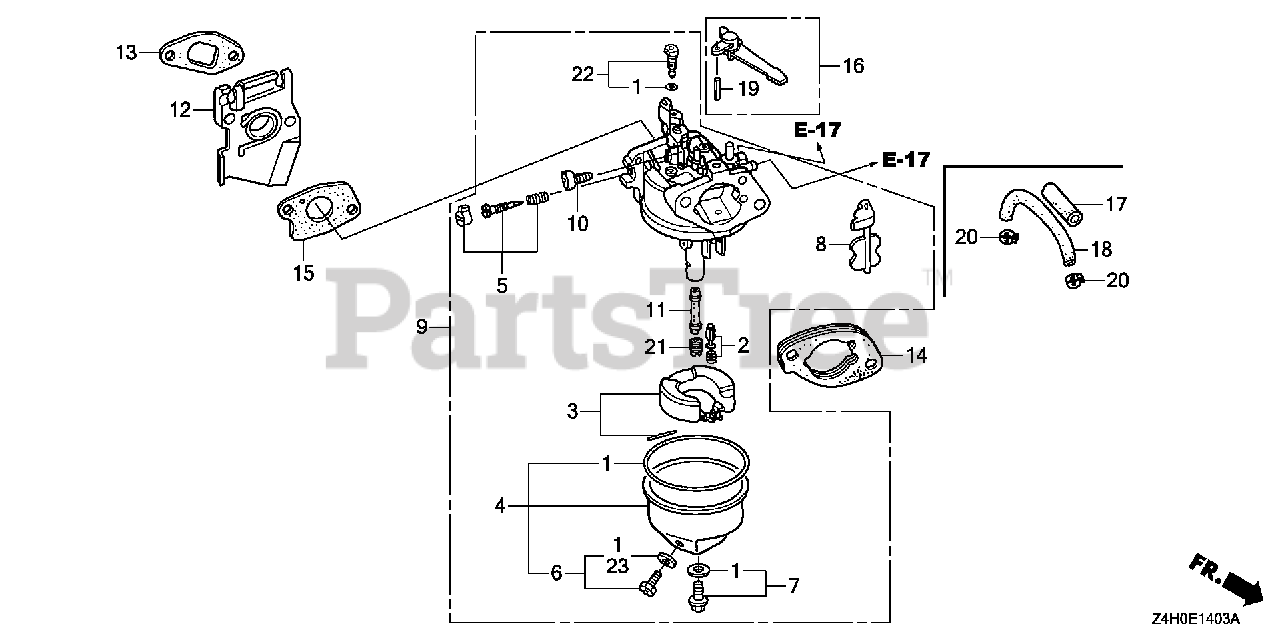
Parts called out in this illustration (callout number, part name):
1	GASKET SET
2	VALVE SET, FLOAT (SEAT NOT INCLUDED)
4	CHAMBER, FLOAT
5	SCREW SET, PILOT
6	SCREW SET, DRAIN
9	CARBURETOR ASSY. (BE62L A)
9	CARBURETOR ASSY. (BE62J A)
10	SCREW, THROTTLE STOP
11	NOZZLE, MAIN
12	INSULATOR, CARBURETOR
13	GASKET, INSULATOR
14	SPACER, CARBURETOR
15	GASKET, CARBURETOR
16	LEVER, CHOKE (STD)
19	PIN, SPRING (2X12)
21	JET, MAIN (#58)
21	JET, MAIN (#60)
21	JET, MAIN (#62)
22	JET SET, PILOT (#35)
